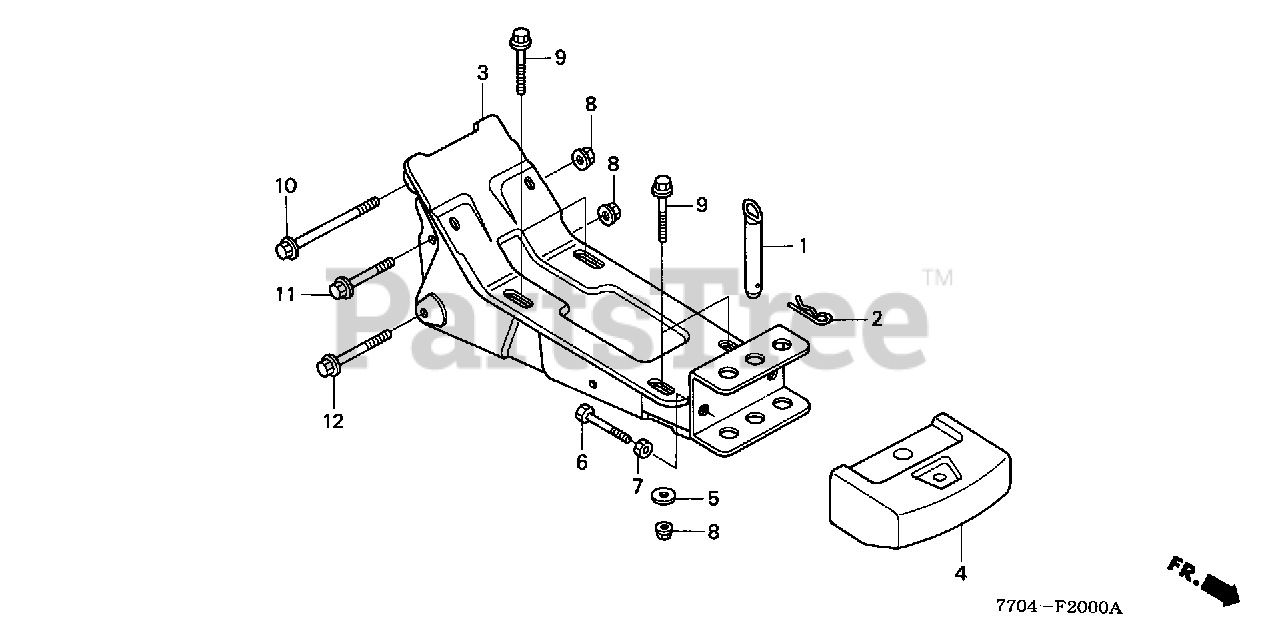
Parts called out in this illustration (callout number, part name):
1	PIN, HITCH
2	PIN, LOCK
3	BED, ENGINE
4	WEIGHT, FR. (8KG) *R280* (POWER RED)
5	WASHER (8X22)
6	BOLT, HEX. (10X32)
7	NUT, HEX. (10MM)
8	NUT, FLANGE (8MM)
9	BOLT, FLANGE (8X35)
10	BOLT, FLANGE (8X80)
11	BOLT, FLANGE (8X40)
12	BOLT, FLANGE (8X55)
